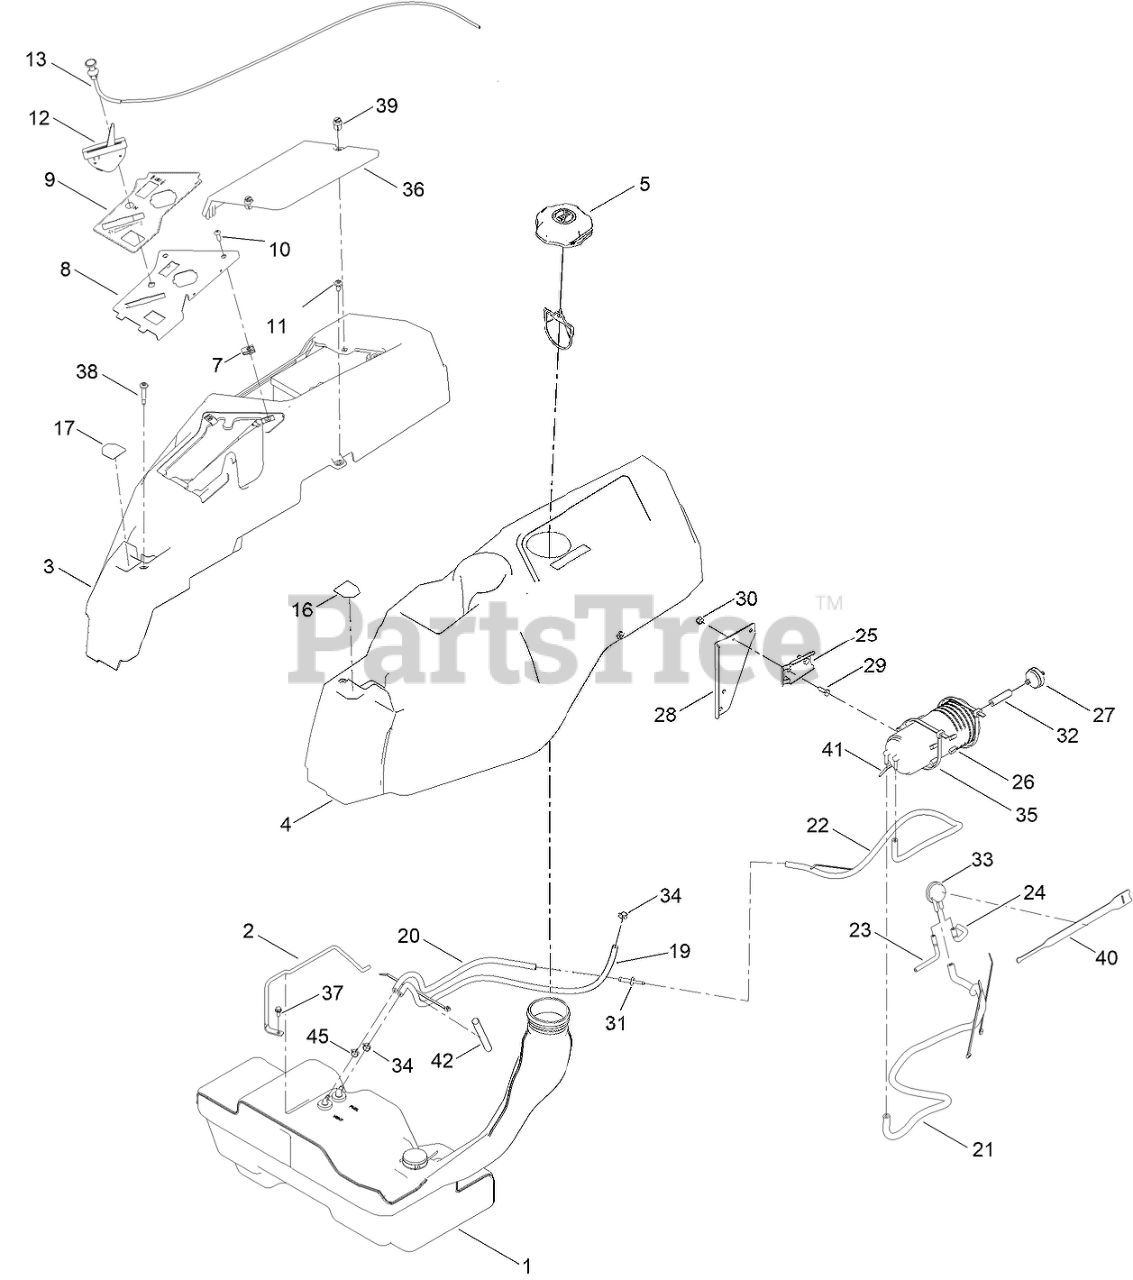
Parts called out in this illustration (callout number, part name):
1	TANK-FUEL ASM
2	ROD-HOLD DOWN
3	POD-RH
4	POD-LH
5	CAP-FUEL, RATCHETING
8	PANEL-CONTROL
9	DECAL-PANEL, CONTROL
10	SCREW-PRH
11	SCREW-SHOULDER
12	CABLE-THROTTLE
13	CABLE-CHOKE
16	DECAL-LEVER, CONTROL (LH)
17	DECAL-LEVER, CONTROL (RH)
19	HOSE-FUEL
20	HOSE-VENT
21	HOSE-FUEL
22	HOSE, FUEL
23	HOSE-VENT, FORMED
24	HOSE-VENT, FORMED
25	BRACKET-CANISTER, CARBON
26	CANISTER-CARBON, 800CC
27	FILTER-FUEL, INLINE
28	CARB CANISTER BRACKET
29	SCREW-HH
30	NUT-LOCK, NI
31	ADAPTER ORIFICE
32	HOSE-FUEL
33	VALVE-CONTROL, VACUUM
34	CLAMP-HOSE
35	TIE-CABLE
36	COVER-BATTERY
37	SCREW-HWH
38	SCREW-SHOULDER
39	FASTENER
40	STRAP-VELCRO, CABLE TIE
41	TIE-CABLE
42	SLEEVE-FUEL LINE PROTECTOR
45	CLAMP-HOSE
